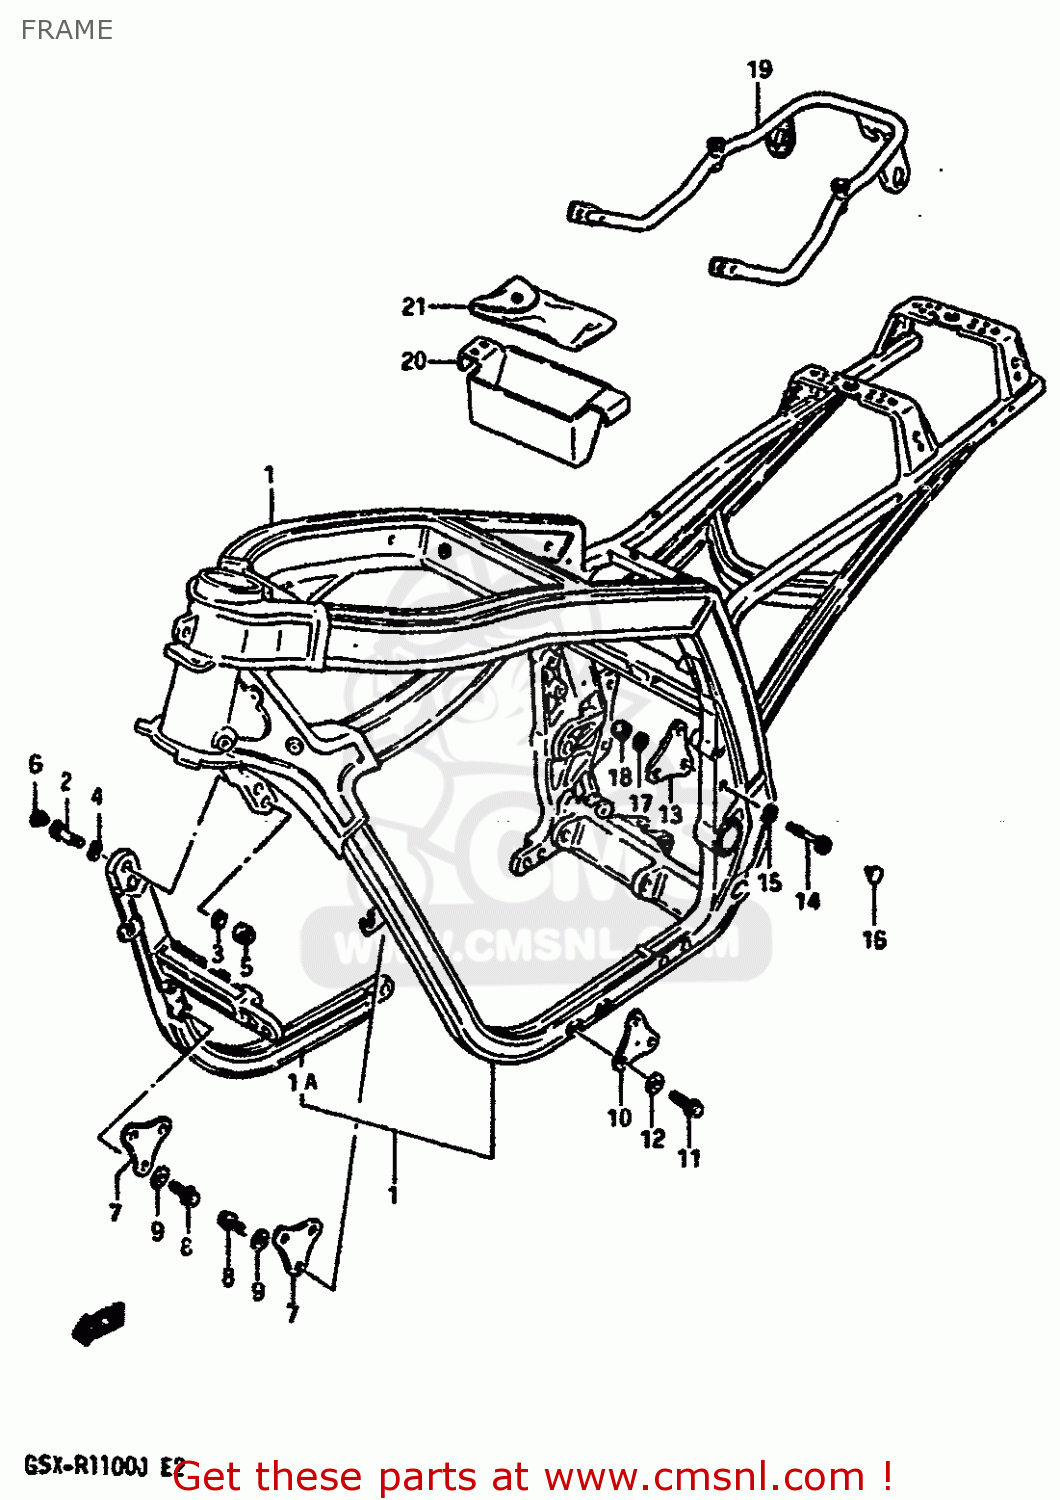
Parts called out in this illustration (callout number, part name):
1	FRAME SET
1A	TUBE COMP,DOWN,RIGHT
2	BOLT
3	WASHER (10.1X21X2.3)
4	WASHER
5	NUT
6	CAP
7	PLATE,ENGINE MOUNTING
8	BOLT
9	WASHER (8.2X20X1.6)
10	PLATE,ENGINE MOUNTING
11	BOLT
12	WASHER (8.2X20X1.6)
13	PLATE,ENGINE MOUNTING
14	BOLT, RH
15	WASHER
16	CAP,ENGINE MOUNTING
17	WASHER,LOCK
18	NUT
19	GRIP COMP,REAR
20	HOLDER,TOOL
21	TOOL ASSY
